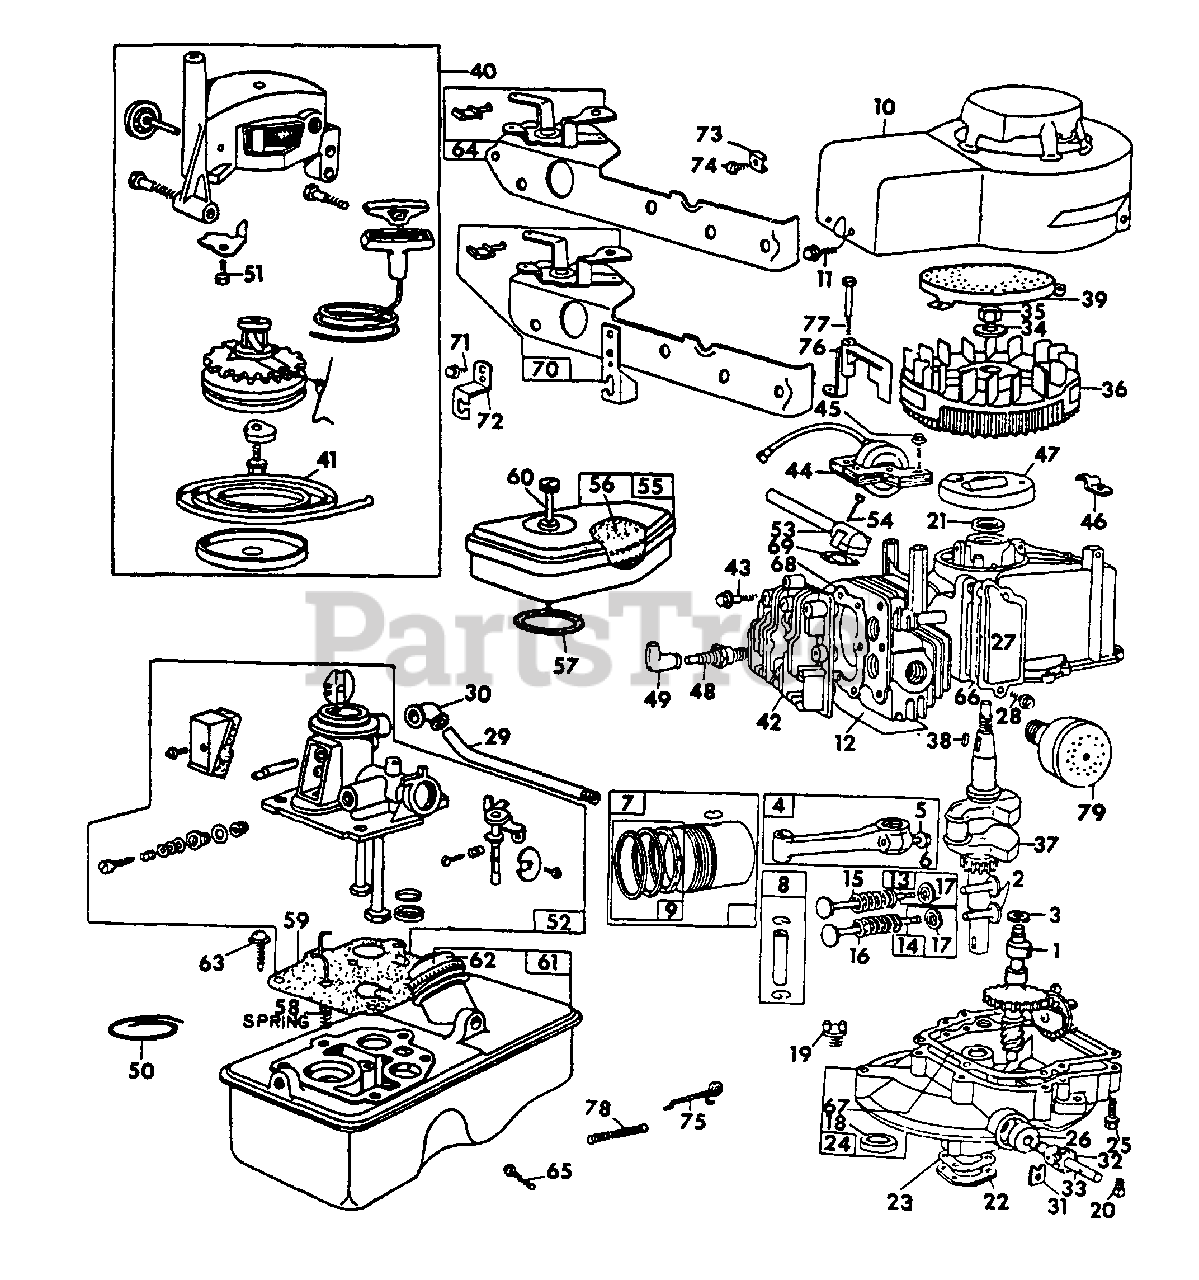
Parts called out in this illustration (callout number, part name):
1	CAM W/GEAR WORM AND OIL SLINGER
2	TAPPET VALVE
3	WASHER, THRUST
4	ROD ASSY, CONNECTING - STD
5	LOCK, SCREW HEAD
6	SCREW, CONNECTING ROD
7	PISTON ASSY - STD
8	PIN, PISTON & RETAINER - STD
9	RING SET, PISTON CHROME - STD
9	RING SET, PISTON - STD
10	HOUSING, BLOWER
11	SCREW, BLOWER HOUSING MOUNTING
12	SHIELD, CYLINDER
13	VALVE, INTAKE
14	VALVE, EXHAUST
15	SPRING, INTAKE VALVE
16	SPRING, EXHAUST VALVE
17	RETAINER, VALVE SPRING
19	PLUG, OIL FILLER
20	PLUG, 3/8-18 AUTOMOTIVE
21	SEAL, OIL
22	COVER, SUMP
23	GASKET, SUMP COVER
24	BASE, OIL SUMP
25	SCREW, SUMP MOUNTING
27	BREATHER, VALVE CHAMBER
28	SCREW, BREATHER MOUNTING
29	TUBE, BREATHER
30	GROMMET, BREATHER TUBE
31	SUPPORT, DRIVE SHAFT STOP
32	GEAR, DRIVE 17 T
33	PIN, DRIVE SHAFT
34	WASHER, FLYWHEEL
35	NUT, FLYWHEEL
38	KEY, FLYWHEEL
39	SCREEN, ROTATING
40	STARTER, VERTICAL PULL
41	SPRING, VERTICAL PULL STARTER
42	HEAD, CYLINDER
43	SCREW, CYLINDER
44	ARMATURE, MAGNETO
45	SCREW, ARMATURE MOUNTING
46	CLAMP, CONDENSOR
47	COVER, BREAKER POINT
48	PLUG, SPARK -CHAMPION-
49	ELBOW, SPARK PLUG INSULATOR
50	WIRE, GROUND
51	SCREW, ELECTRIC STARTER
52	CARBURETOR
53	TUBE, FUEL INTAKE
54	SCREW, INTAKE ELBOW MOUNTING
55	CLEANER, AIR
56	ELEMENT, AIR CLEANER
57	GASKET, AIR CLEANER MOUNTING
58	SPRING, DIAPHRAGM
59	DIAPHRAM, CARBURETOR
60	SCREW, AIR CLEANER
61	TANK ASSY, FUEL
62	CAP, FUEL TANK
63	SCREW, FUEL TANK MOUNTING
64	PLATE, CARBURETOR CONTROL
65	SCREW, FUEL TANK TO STARTER MOTOR
66	GASKET, VALVE COVER
68	GASKET, CYLINDER HEAD
69	GASKET, INTAKE ELBOW
70	BRACKET, CARBURETOR CONTROL PLATE
71	SCREW, 8/32 X 3/4 HEX-HD TAP
72	CLIP, HARNESS PLUG RETAINER
73	CLAMP, CASING
74	SCREW W/LOCKWASHER, HEX-HD
75	LINK, GOVERNOR
76	BLADE, GOVERNOR
77	SCREW
78	SPRING, GOVERNOR
79	MUFFLER, EXHAUST
